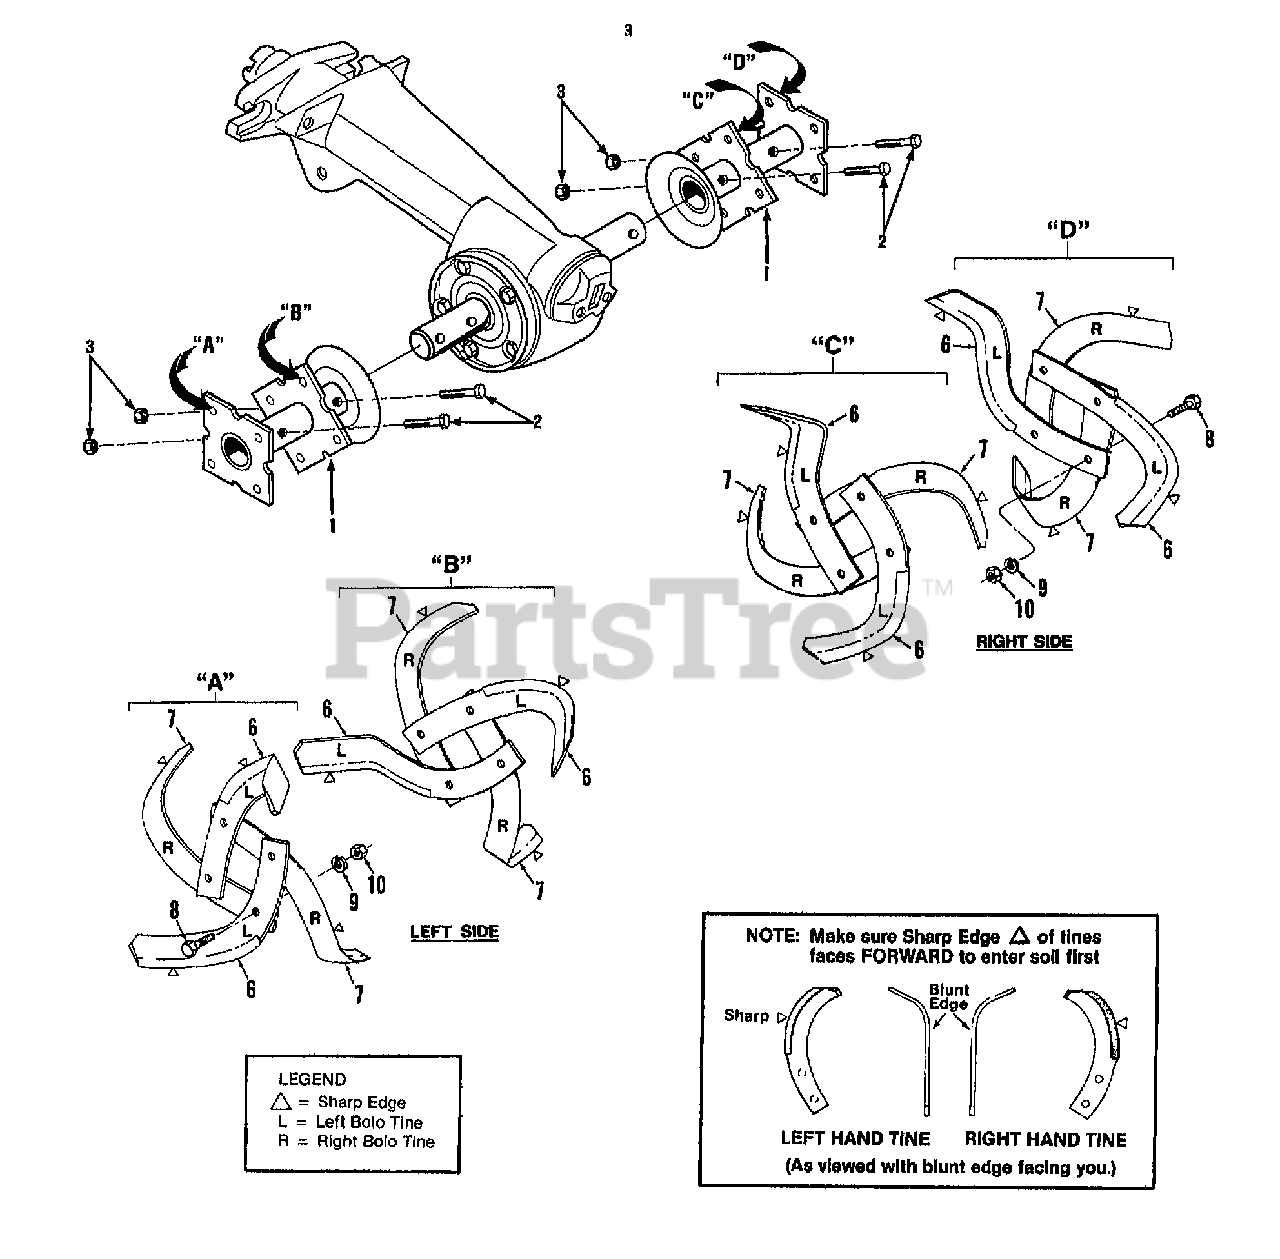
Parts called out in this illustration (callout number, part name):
1	HOLDER-TINE HORSE (RED)
2	SCR-HH 3/8-16X2.00 G8
3	NUT-H/LK 3/8-16
6	TINE-BOLO LT W/HDW(INCL. TWO EACH OF REF. NO.'S 8,9 AND 10)
7	TINE-BOLO RT W/HDW(INCL. SAME HARDWARE AS REF. NO.6)
8	SCR-HH 3/8-16X1.0 G5 ZP
9	WASHER-LK .375 @ DEPL
10	NUT-HEX 3/8-16 ZP
